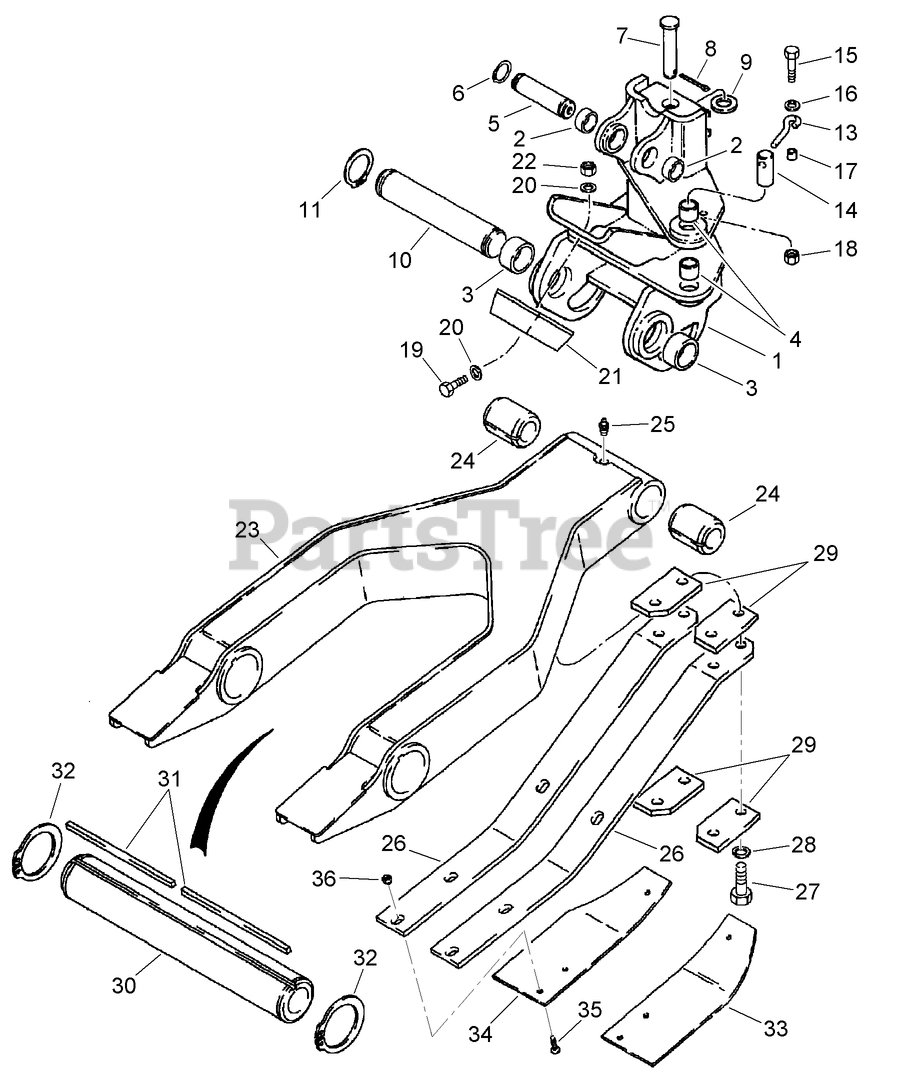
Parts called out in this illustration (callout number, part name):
1	TOWER - Plow Swing
2	BUSHING-plow swing tower, upper pivot
3	BUSHING-25 mm (1 inch) long, plow swing tower, lower pivot
4	BUSHING-arm, 25 mm (1 inch) ID, plow swing tower, swing cylinder pivot
5	PIN-pivot, swing tower, small
6	RING-RETAINING
7	PIN-CLEVIS
8	PIN-Cotter 0.25 x 2.00 in ZN
9	WASHER-FLAT
10	PIN-pivot, 10-7/8 inch long, swing tower, large
11	RING-RETAINING, EXTERNAL
13	PIN-RETAINER
14	PIN-pivot
15	BOLT-hex, 5/16 NC x 1-3/4 inch
16	WASHER-FLAT
17	SPACER-13 mm (1/2 inch) long
18	NUT-HEX
19	BOLT
20	WASHER-FLAT
21	BUMPER
22	NUT-HEX
23	ARM-plow lift
24	BUSHING-ARM, PLOW
25	FITTING-grease, 45 degree, 1/8 PT self-tap x 25/32 inch
26	SHOE-skid, plow
27	BOLT-Hex Hd 1/2 x 1-3/4 GR5 ZND
28	WASHER-Spring Lock Reg 1/2 ZND
29	PLATE-skid shoe support
30	PIN-pivot, rear
31	KEY-square, 9.5 x 250 mm, plow pivot pin, rear
32	RING-external retaining, No. 300, rear plow pivot pin retaining
33	PLATE-skid shoe, right-hand
34	PLATE-skid shoe, left-hand
35	BOLT-hex socket head, 3/8 NF x 1 inch, grade 8
36	NUT-hex jam, self-locking, 3/8 inch NF
